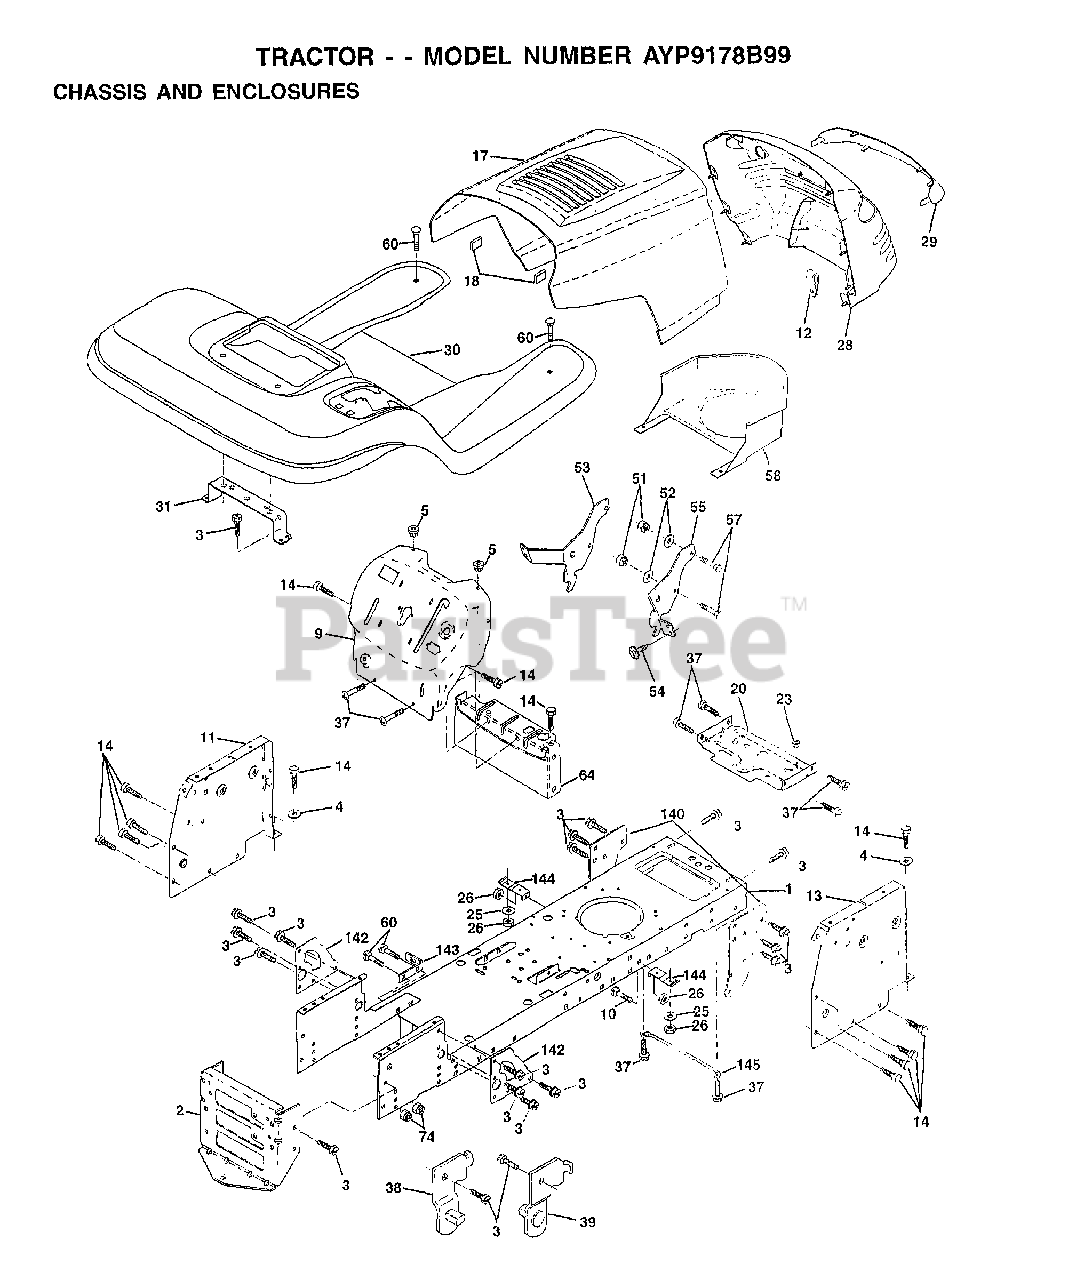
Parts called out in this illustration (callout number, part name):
1	CHASSIS.STLT.STAMPING
3	SCREW
4	WASHER
5	BUMPER-HOOD/DASH
11	"PANEL-DASH,LH"
12	CLIP.TINNERMAN
13	PANEL.ASM.DASH.RH
14	SCREW LT
17	HOOD.STEEL.ASSY
20	"PLATE-MTG,BATT/FU"
25	WASHER
26	NUT
28	GRILL
29	GRILLE.LENS
30	FEND/FTREST PNT
31	BRACKET SUPT FEND
37	SCREW LT
38	BRACKET ASM LH
39	BRACKET ASM RH
51	NUT
52	WASHER
53	BRACKET.GRILLE.LH
54	SCREW.HEX.WS.HD
55	BRACKET.GRILLE.RH
58	AIR DUCT
60	BOLT
64	DASH-LOWER
140	BRKT SUSPENSION
142	PLATE.REINFORCEMENT
143	"BRKT-S'BAR,CHASSI"
144	BRKT-FOOTREST
145	"ROD POVOT,CHASSIS"
